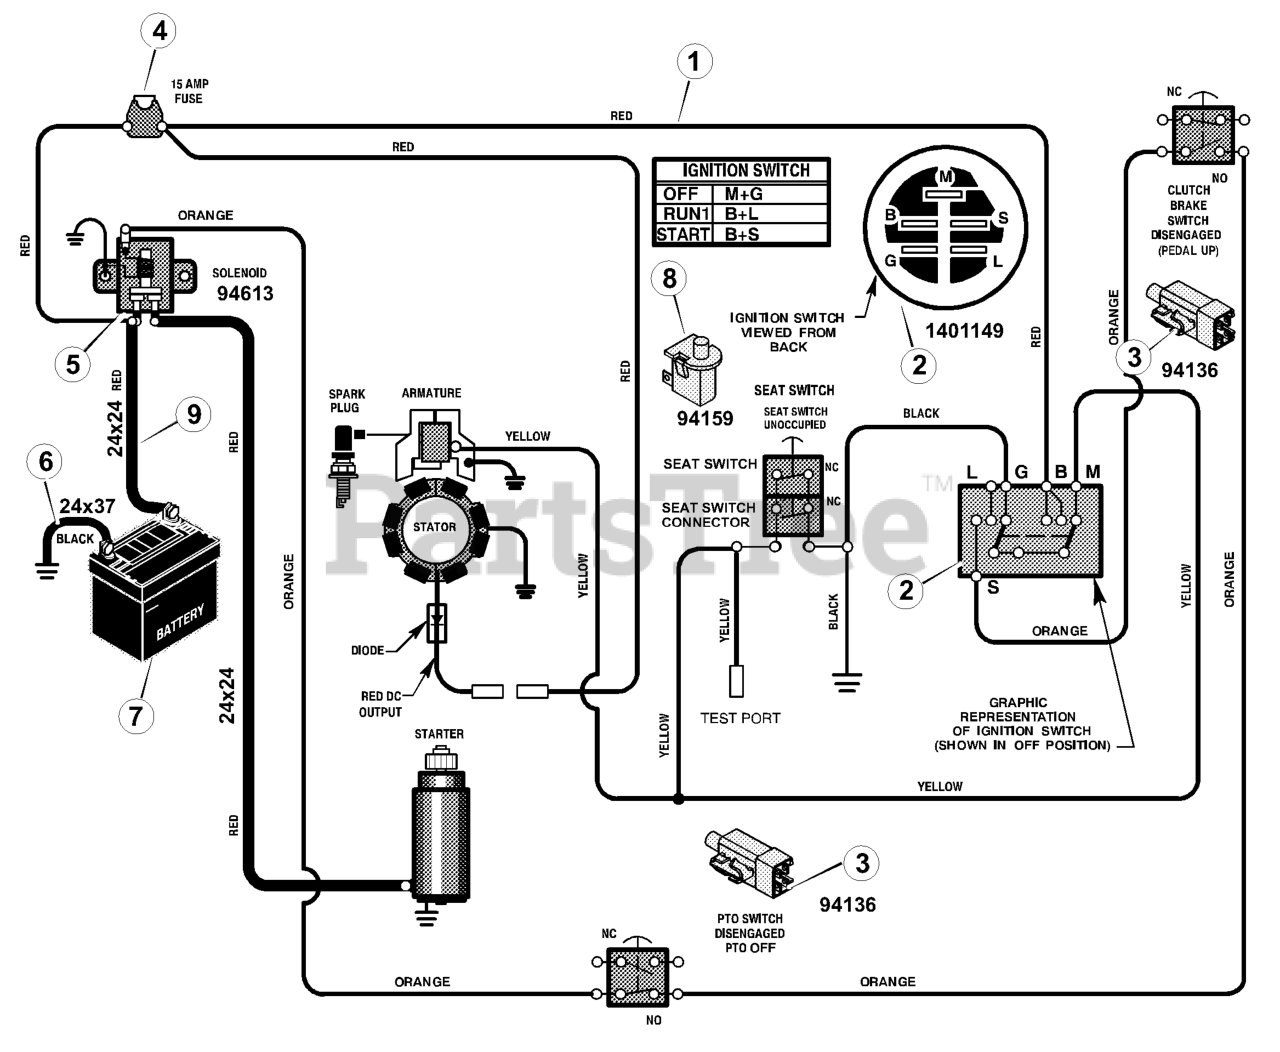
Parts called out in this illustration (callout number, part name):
1	Harness, Chassis Wire
2	Switch, Ignition
3	Switch, Limit
5	Solenoid
6	Cable, Battery Ground
7	Battery
8	Switch, Seat Sensor
9	Cable, Red Battery
